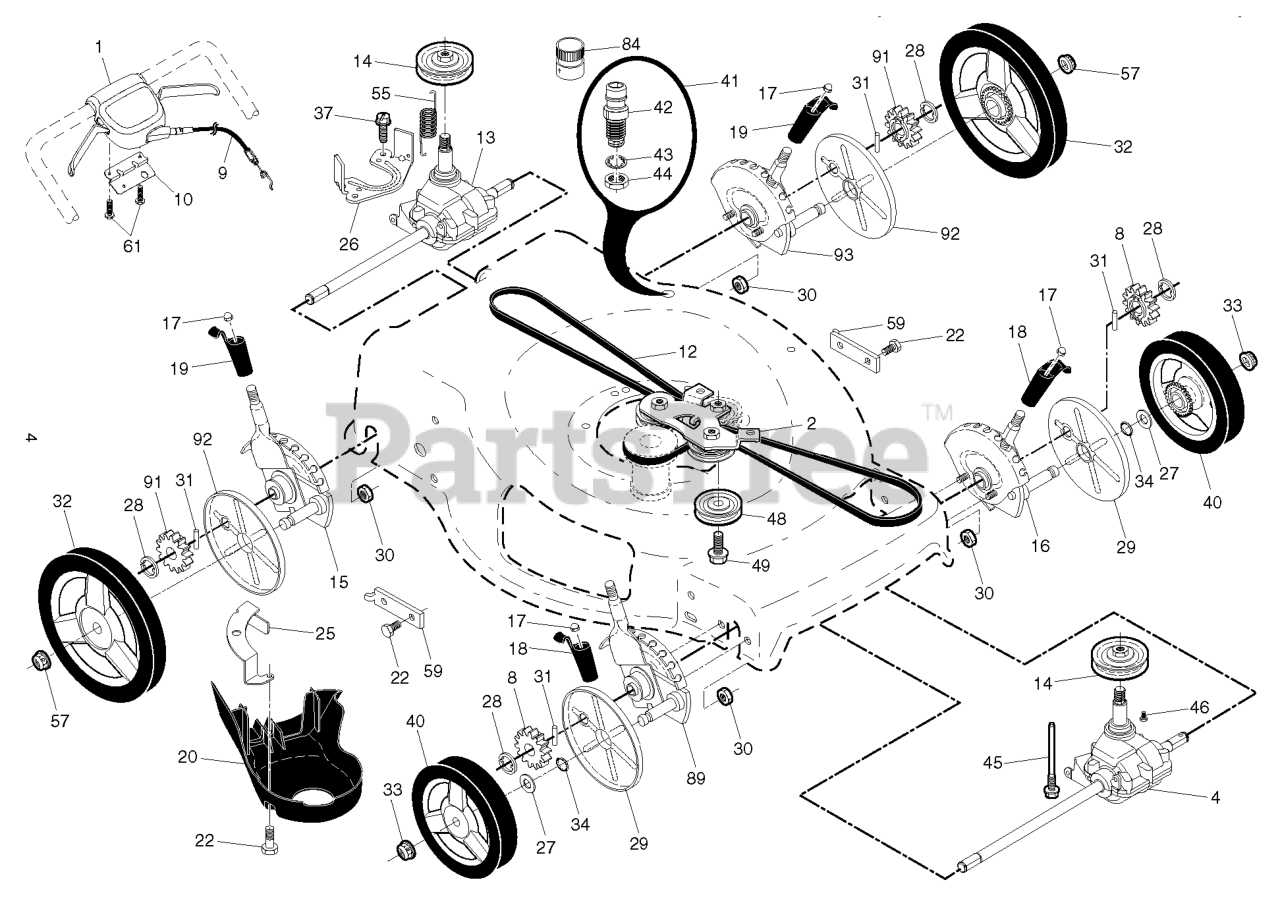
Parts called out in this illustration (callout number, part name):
1	HOUSING.TRANSAXLE.70536
2	ASSEMBLY, RH HOUSING
7	SEAL.OIL.44782.HY (44782)
16	BRAKE SHAFT KIT #62877
20	AXLE.MOUNTING.HORN.70087
21	WASHER 44805
33	BRAKE YOKE ASSEMBLY
35	BRACE ARM 50214
36	PUCK PLATE 44134
37	BRAKE PUCK (44132)
38	WASHER .34X.88X.06.44130
39	CASTLE NUT
40	PIN.COTTER.44101.
41	BRAKE PIN 44127
42	KEY.HIPRO.44143
43	SPACER 50259
45	BRAKE.DISC.44090.
46	BOLT 44276
47	BOLT W/NYLOCK 44433
49	DIFFERENTIAL ASSEMBLY
63	DOWEL.PIN.44757.HYDRO
64	REDUCTION GEAR/14-38 TEETH
65	PINION DR FINAL 70051
67	JACKSHAFT.44779.HYDRO
68	O-RING #44781
69	WASHER.44795.
70	WASHER.44794.HYDRO
71	BOLT HXHD 44827
72	NUT 5/16-18 HEX LOCK 43064
73	BOLT, HEX5/16-18X1-1/2
74	HEX CAP SCREW, 5/16-18X1
76	BOLT.SHOULDER.44785.
77	FREE WHEEL ACTUATING ARM 44786
78	SEAL OIL 70719
79	GREASE (10 OZ TUBE)
82	BOLT 5/16 44820
89	FILTER
91	PUMP.BDU-10L-122
95	PLUG.9005110-5600
103	WASHER 50169
104	CAP, VENT ASSY
106	O-RING KIT 70110
108	ARM CONTROL 45007
109	SCREW.SET.50018
110	FILTER HEAD 50207 HYDRO
113	FITTING, 1/2" BEADED 60 -9/16
117	FITTING.SAE.50589.HYDRO GEAR
123	O-RING 50405
124	CLAMP 50590
129	SPRING.LONG.50667
